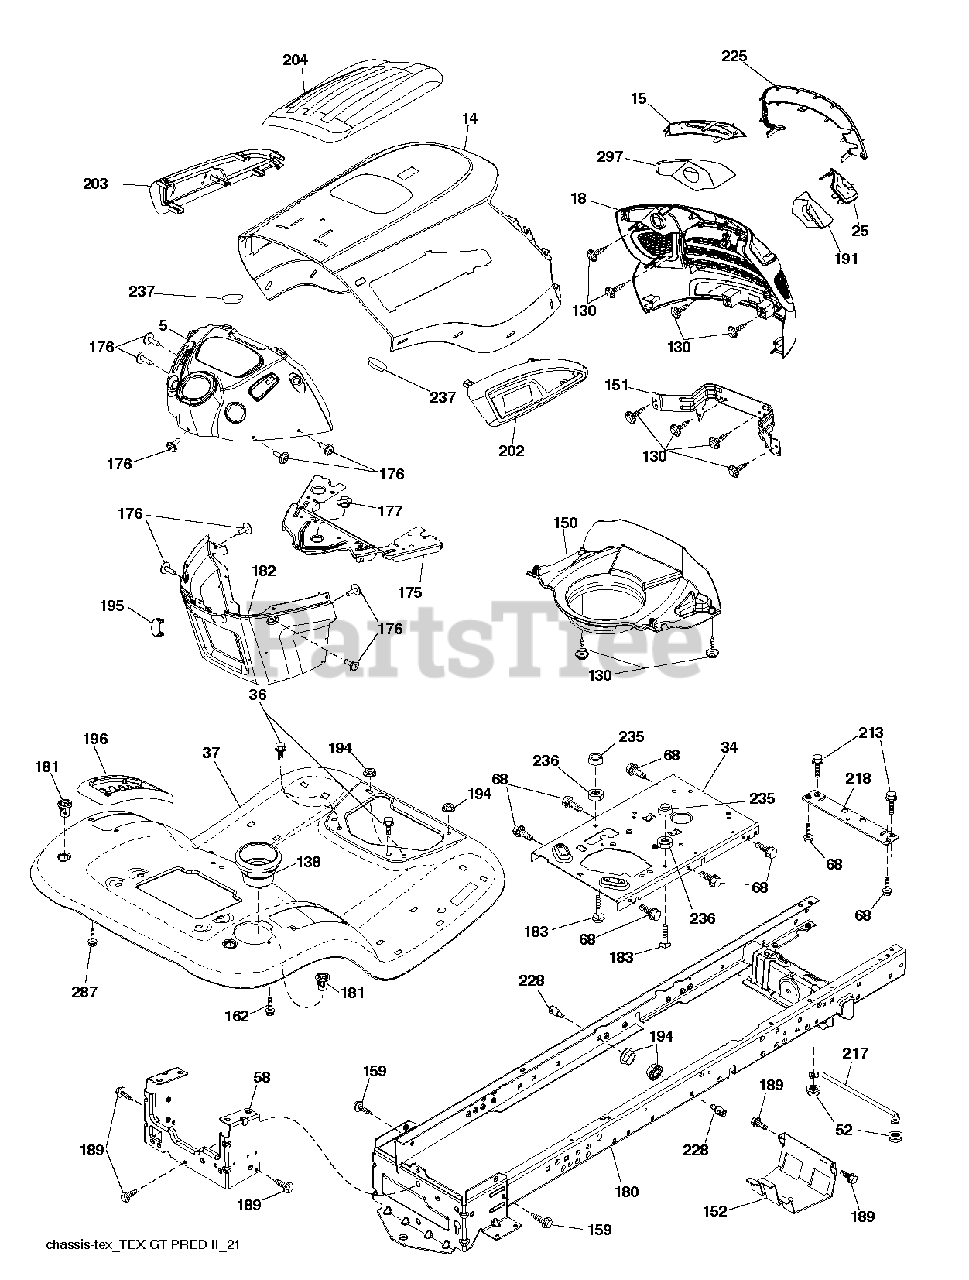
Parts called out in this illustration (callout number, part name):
5	DASH.UPPER.PREDATOR.M/C.BLACK
14	HOOD.PREDATOR.YT/GT.PNT428
15	LENS.MCCULLOCH.GT.LH
18	GRILLE.PREDGT2.GEN
25	Lens, RH Mcculloch GT
34	PLATE.ENGINE.WELDED.CHASSIS
36	SCREW 5/16"
37	FENDER.TLT.W/CPH.428
52	LOCKNUT
58	DRAWBAR UPPER 2PC SMALL FENDER
68	SCREW LT
130	SCREW.#10 X 0.750.BOS (2 2)
138	CUPHOLDER.TL.TEX.BLACK
150	PREDATOR.YT.GT.HOOD.AIR DUCT
151	BRACKET.PIVOT.PREDATOR
152	SHIELD.BROWNING.W/TEX
159	SCREW, 3/8-16X3/4
162	SCREW.HI-LO.CONSOLE
175	PLATE.CROSSMEMBER.HUSQ
176	SCREW.#10-24X5/8.RN.QU
177	BUSHING STEERING
180	CHASS.WLDMNT.TL.12GA/2P.48/54
181	FEND/FTRST.PCH.CPH.NFW
182	DASH LOWER.HUSQ.PRED NO CRUISE
183	BOLT.5/16-18X1-1/4 FULL THD
189	SCREW
191	REFLECTOR.MCCULLOCH.GT.RH
194	NUT LOCK HEX FLANGE 5/16-18
195	PLUG.HOLE.DASH.
202	VENT.SIDE.HOOD.RH.PREDATOR
203	VENT.SIDE.HOOD.LH.PREDATOR
204	VENT ASM.TOP.PRED GT PRO.428
213	BOLT
217	ROD.PIVOT.HOOD
218	X-PIECE.HOOD.STOP.NON/
228	STUD.FASTNER.W/ANTI-ROTATE
235	SPACER FENDER
236	NUT.CENTERLOCK.5/16-
237	PLUG.MOUNT.CARGO.BLK
287	SCREW 1/4X20
297	REFLECTOR.MCCULLOCH.GT.LH
